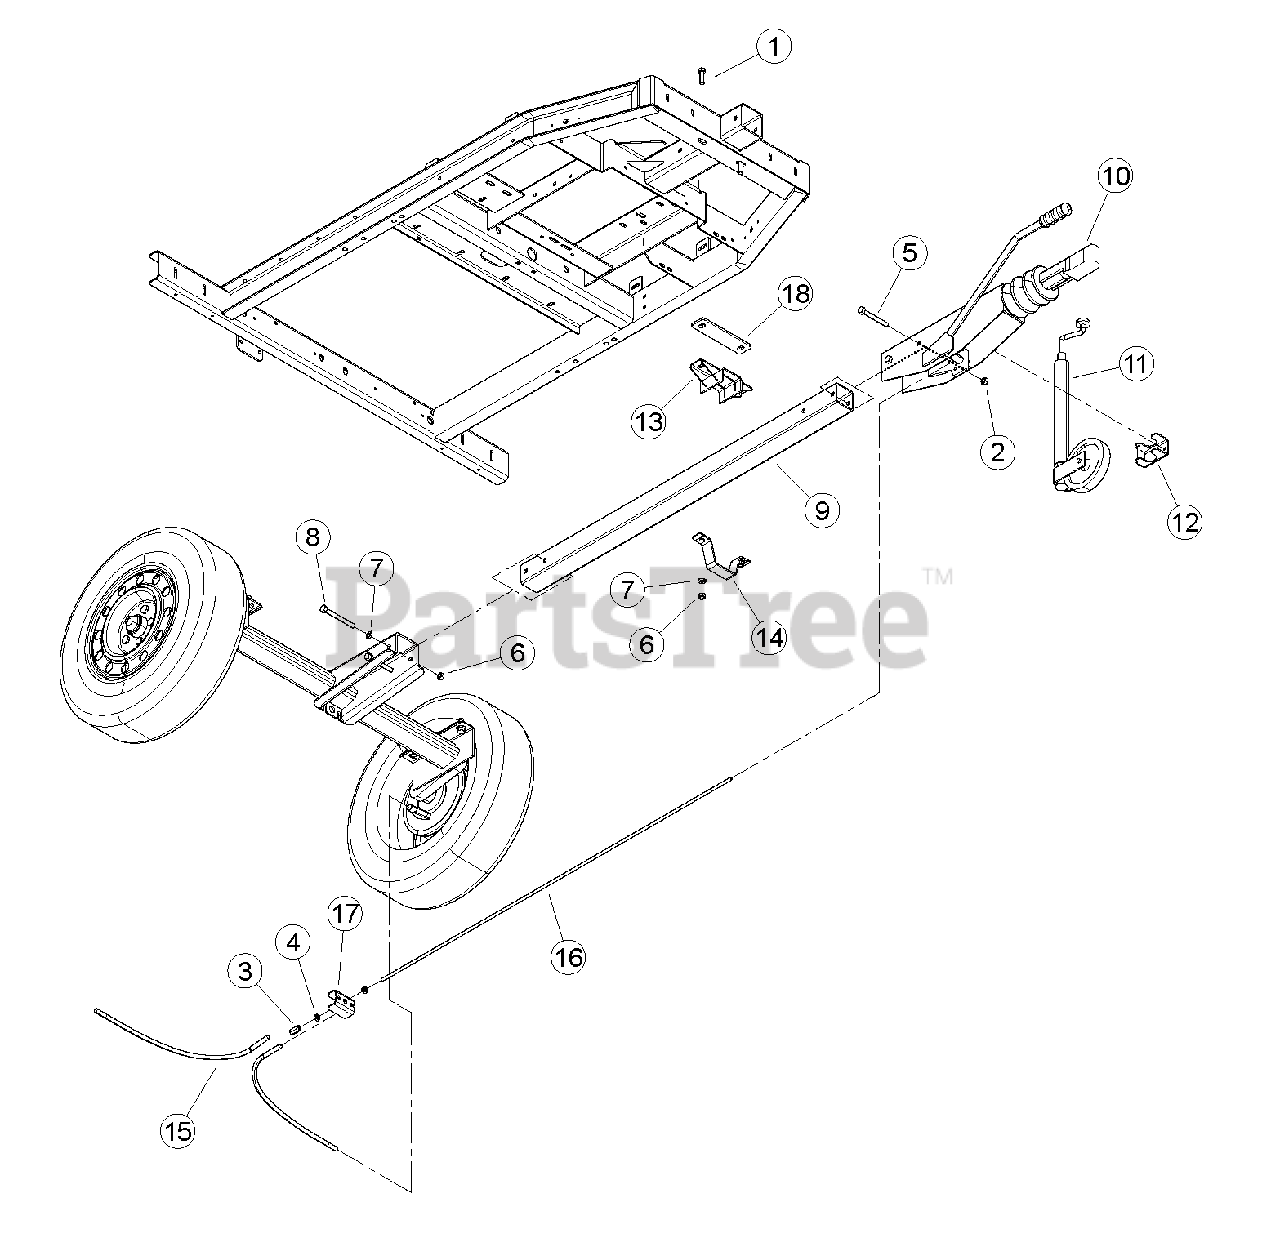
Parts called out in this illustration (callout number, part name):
1	BOLT, M12 X 1.75 X 40 GR8.8 HCPS
2	NUT, M12 X 1.75 HEX NYLOCK TYPE NEY ZP
3	BOLT, 12MM LUG FOR WHEELS
4	NUT, SPHERICAL M10 X 35MM
5	NUT, M10 HEX
6	BOLT, M12 X 100 CLASS 10.9
7	NUT, M12 HEX
8	WASHER, M12 FLAT
9	BOLT, M12 X 120 CLASS 10.9
10	DRAWBAR, 70MM X 70MM
11	COUPLER, 50MM W/ BRAKE HANDLE
12	JACK, JOCKEY WHEEL
13	CLAMP, JOCKEY WHEEL
14	MOUNT, FRONT DRAWBAR
15	CLAMP, FRONT DRAWBAR
16	CABLE, AXLE BRAKES SHORT
17	ROD, BRAKE CONTROL
18	BRACKET, BALANCE BAR
19	PLATE, DRAWBAR MOUNT
